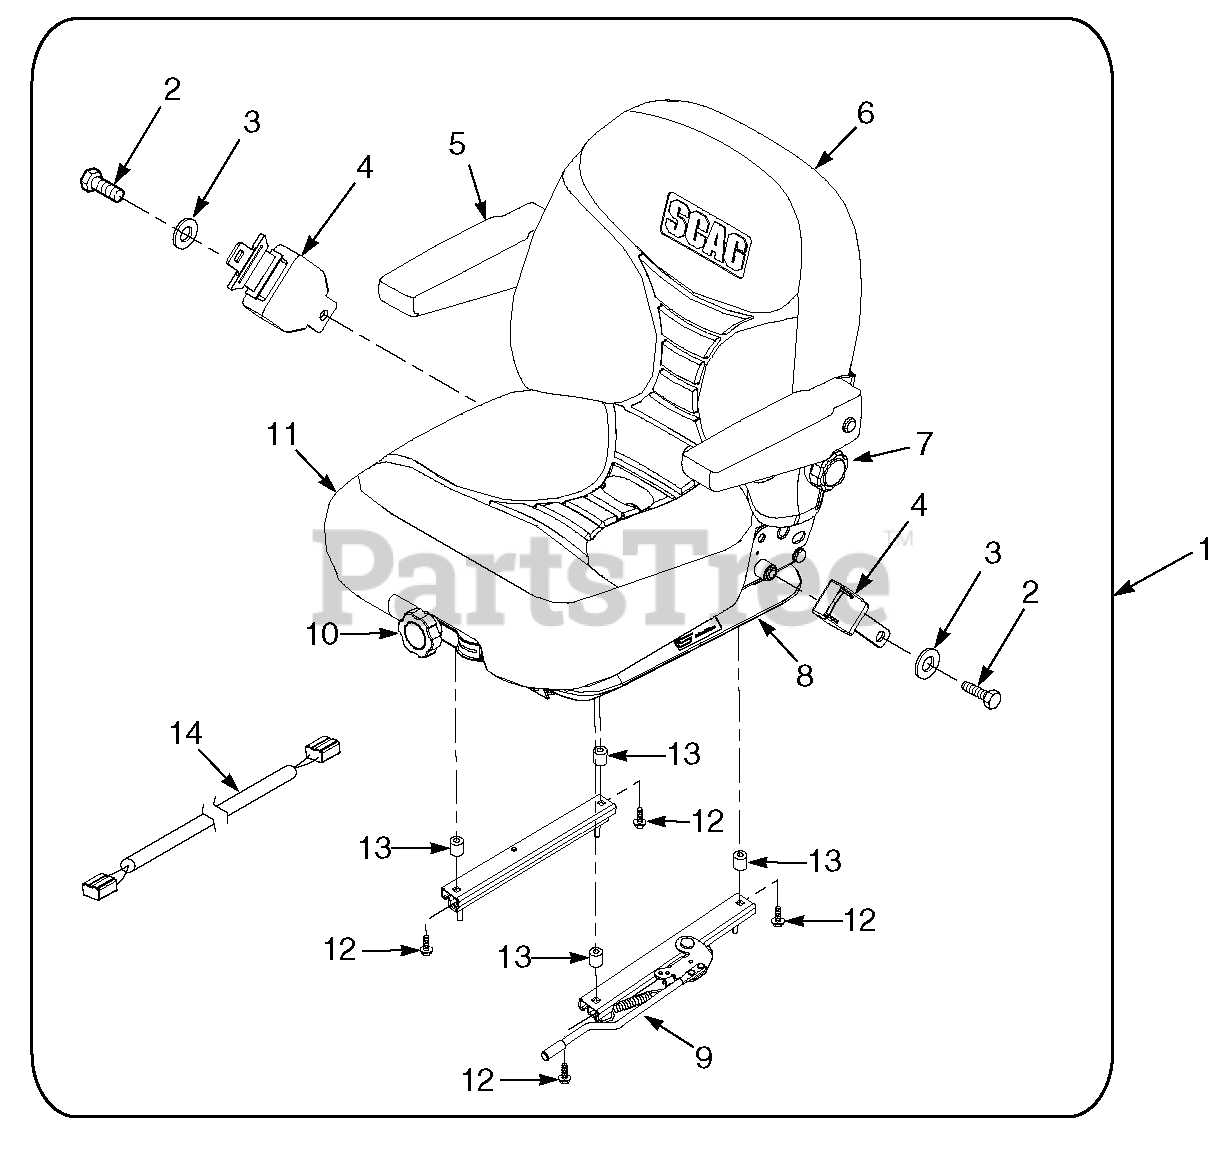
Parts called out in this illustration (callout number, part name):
1	Suspension Seat Assembly w/seat belt
2	Bolt, Hex Head 7/16-20 x 1"
3	Flatwasher, 7/16-.500 x 1.25 x .083
4	Retractable Seat Belt
5	Armrest Only
6	Back Cushion Kit
7	Lumbar Kit
8	Shock Absorber Kit
9	Seat Adjustment, Track Set
10	Weight Adjustment Kit
11	Seat Cushion Kit
12	Bolt, Hex Head 5/16-18 x 1-3/4"
13	Spacer
14	Wire Harness Adapter
